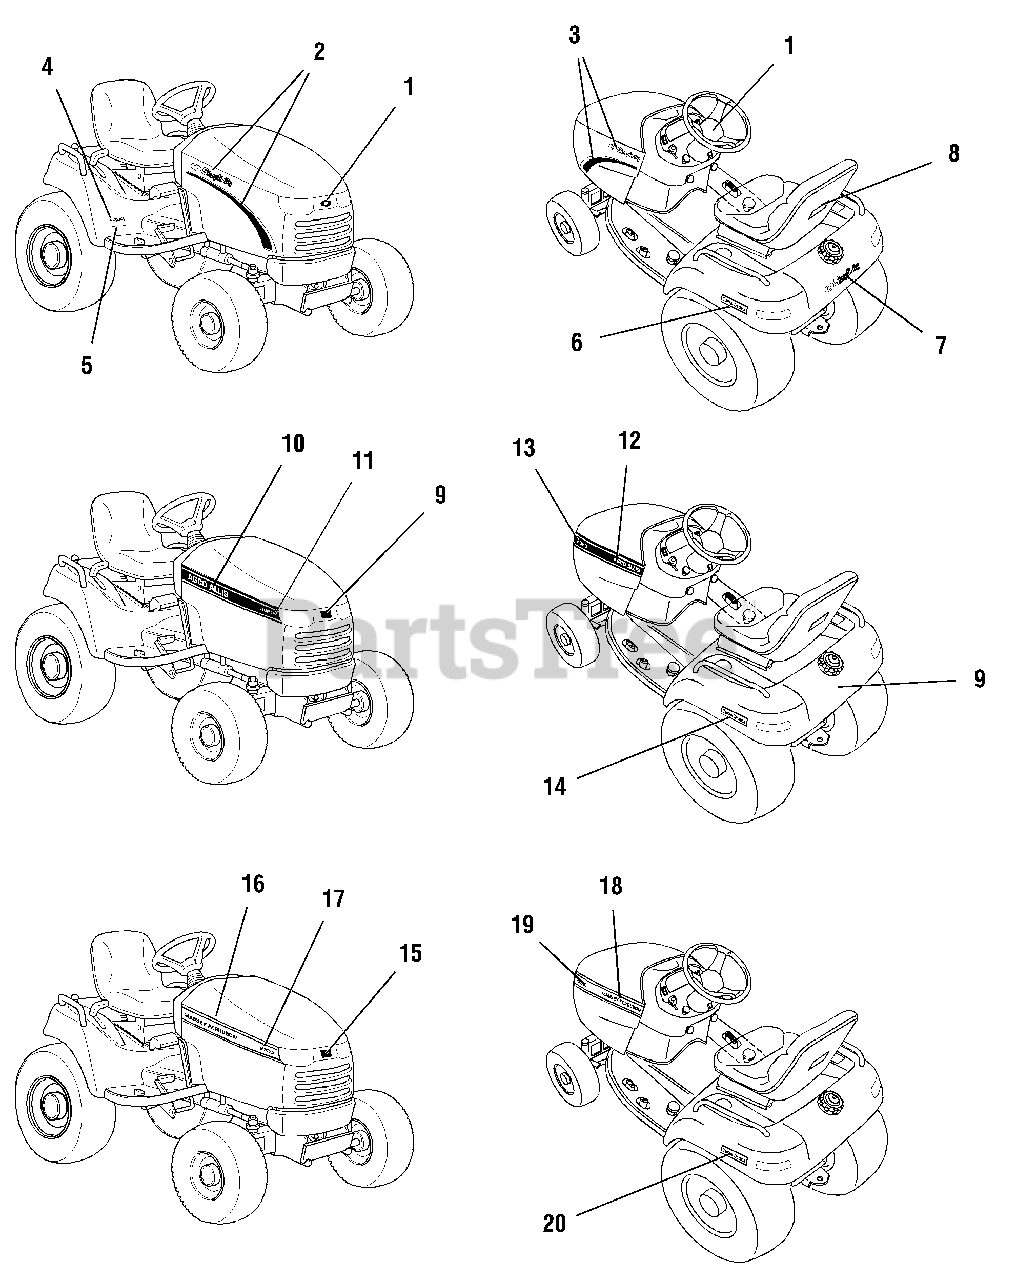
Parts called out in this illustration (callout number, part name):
1	ICON, Simplicity
2	Hood Stripe Decal, RH
3	Hood Stripe Decal, LH
4	DECAL, Legacy
5	DECAL, 24.5 Diesel
6	DECAL, Automatic Control Traction
7	DECAL, Simplicity Logo
8	DECAL, USA Logo
9	DECAL, AGCO Allis Logo
10	DECAL, RH Stripe & Logo
11	DECAL, RH, Model
12	DECAL, LH Stripe & Logo
13	DECAL, LH, Model
14	DECAL, Automatic Control Traction
15	DECAL, Massey Ferguson Logo
16	DECAL, RH Stripe & Logo
17	DECAL, RH, Model
18	DECAL, LH Stripe & Logo
19	DECAL, LH, Model
20	DECAL, Automatic Control Traction
